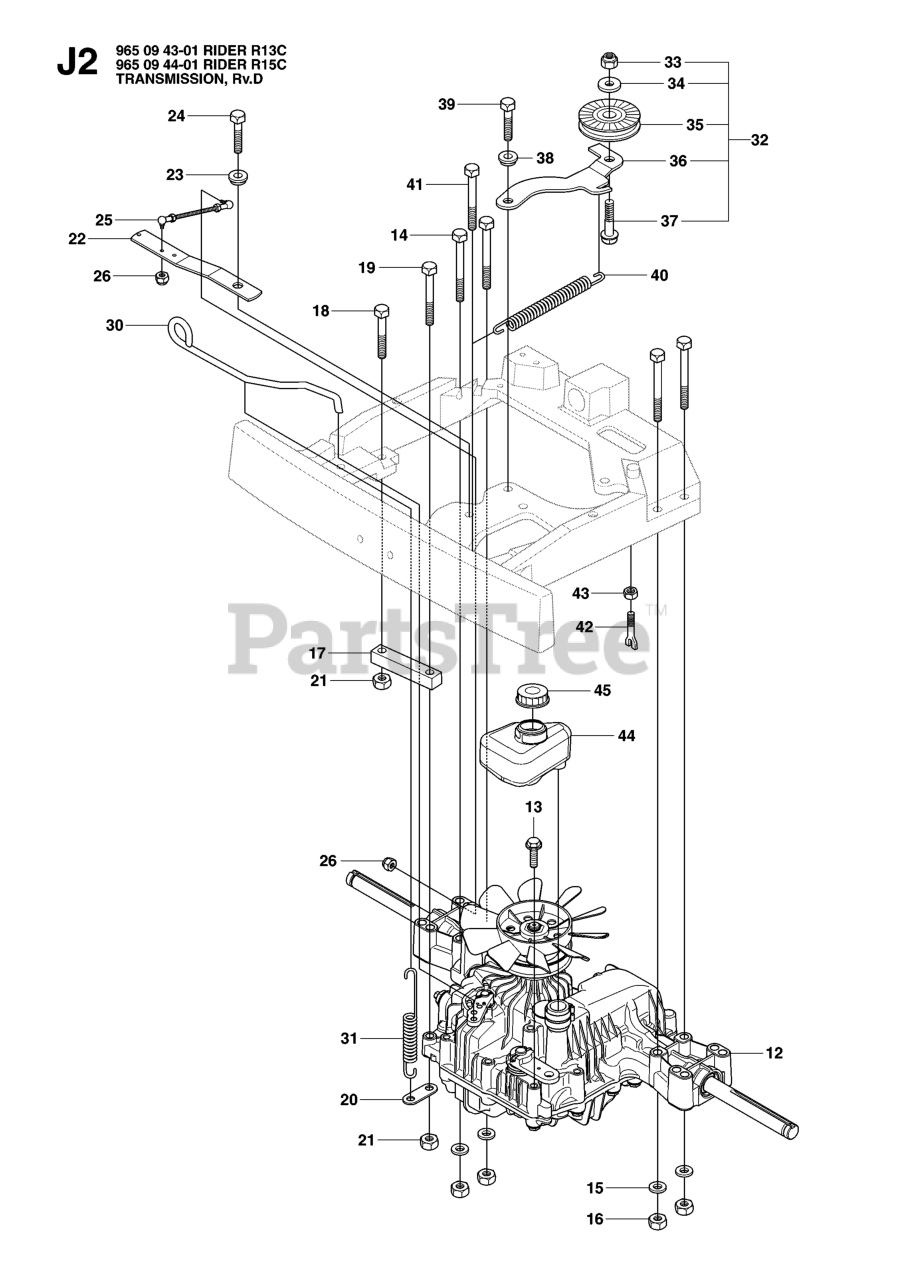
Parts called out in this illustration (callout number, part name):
12	HYDROSTAT 7A646024070
15	WASHER BRB 8.4X17
16	NUT
21	NUT
23	WASHER
24	SCREW 8X20
26	LOCKNUT M5
33	TENSIONER
35	SCREW
37	LOCKNUT M8
38	WASHER
39	SCREW 8X20
43	NUT
45	TANK CAP
